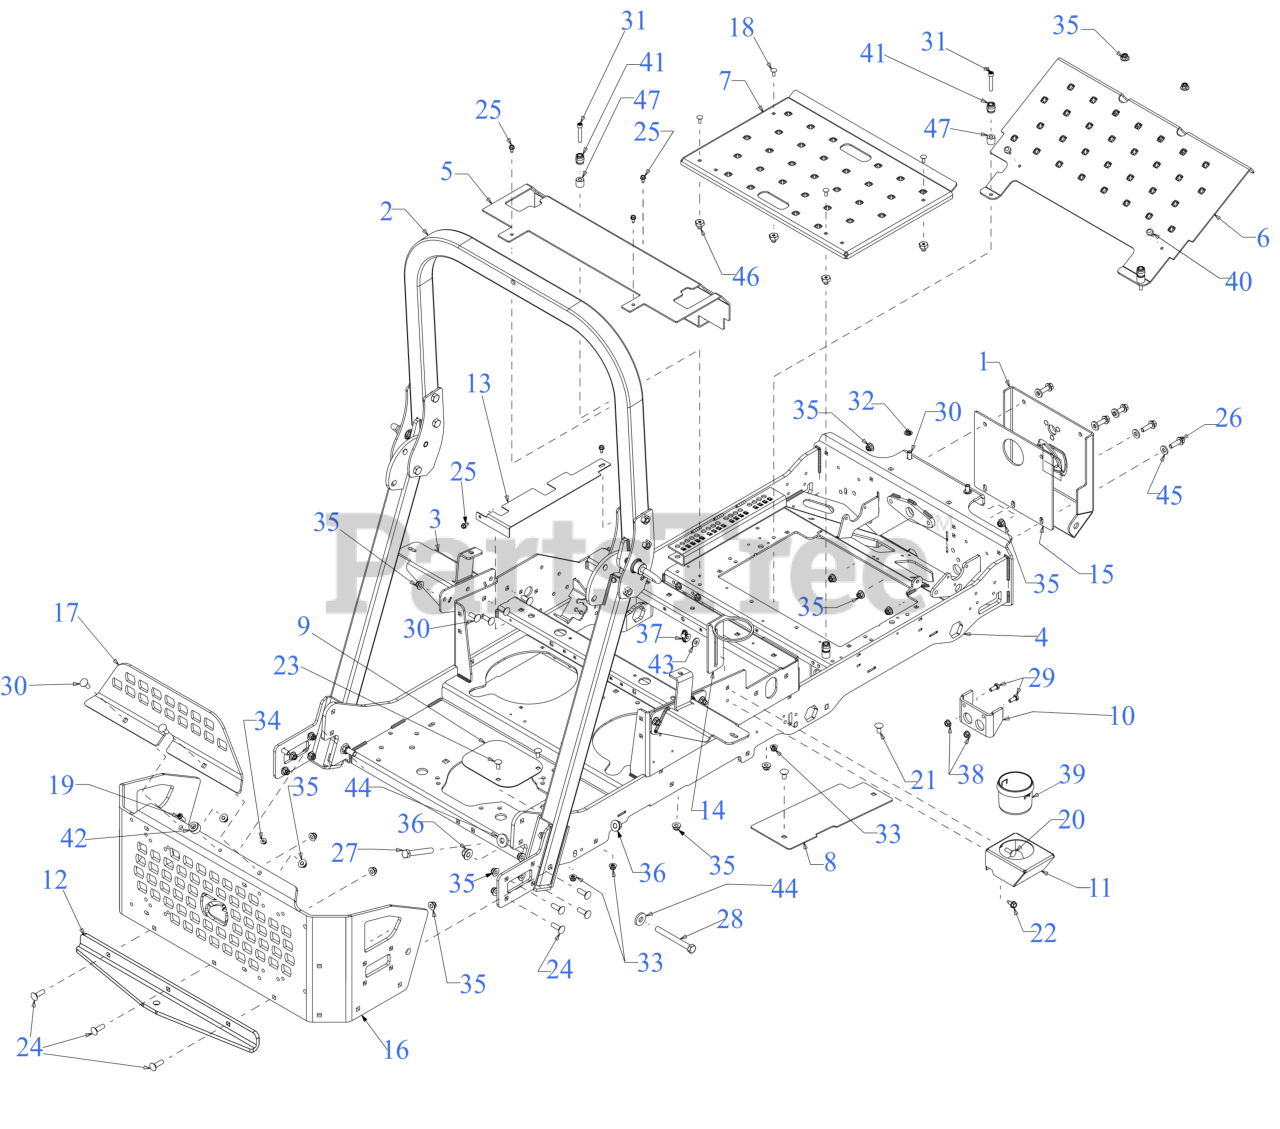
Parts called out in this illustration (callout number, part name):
2	PRO Z ROPS KIT
3	FUEL TANK MOUNT
4	FRAME
10	FRONT DECK LIFT MOUNTING BRACKET
11	LOWER CUP HOLDER
15	FRONT MOUNTING PLATE SPACER
16	BUMPER (REAR)
17	BUMPER (UPPER RR)
18	CARRIAGE BOLT 1/4-20 x .62
19	MACHINE SCREW 1/4-20:1
20	CARRIAGE BOLT 5/16-18 x 1.00
21	CARRIAGE BOLT 3/8-16 x .750 GR5
22	SCREW 5/16-18 x .750
23	CARRIAGE BOLT 5/16-18 x .75
24	CARRIAGE BOLT 3/8-16 X1.25 GR5
25	SCREW 1/4-20 X.500
26	SCREW 3/8-16 x 1.25 GR5
27	HEX SCREW 1/2-13 x 3.50
28	SCREW 1/2-13 x 4.5 GR 5
29	SCREW 5/16-18 x .75 GR5
30	CARRIAGE BOLT 3/8-16 x 1.00 GR5
31	SCREW 5/16-18X1.75 GR5
33	FLANGE LOCK NUT 5/16-18
34	FLANGE LOCK NUT
37	WING NUT 5/16-18
38	HEX FLANGE NUT
40	BUMPER, .62 DIA x .3
41	RADIAL BUMPER
43	FLAT WASHER
44	FLAT WASHER .531 x 1.25 x .181
45	FLAT WASHER
46	SHOULDER SPACER
